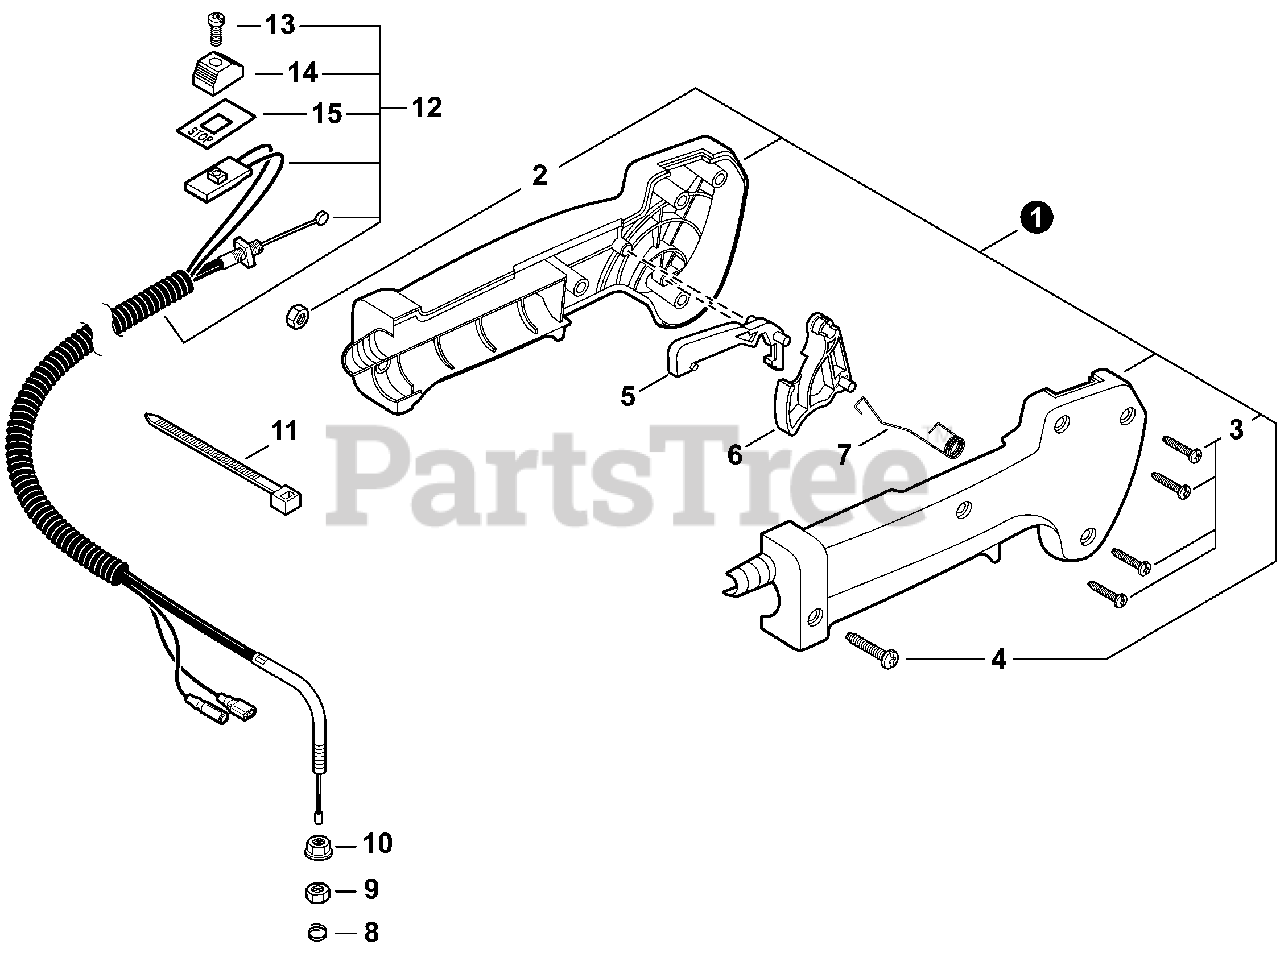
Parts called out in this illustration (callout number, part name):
1	CONTROL HANDLE KIT
3	SCREW 3×25
4	SCREW 5×30
5	LOCKOUT, THROTTLE
6	TRIGGER, THROTTLE
7	SPRING, TORSION
10	NUT, FLANGE M6
11	STRAP, TIE
12	CABLE ASSY, CONTROL
13	SCREW 3×10
14	KNOB, SWITCH - ORANGE
15	LABEL, SWITCH
